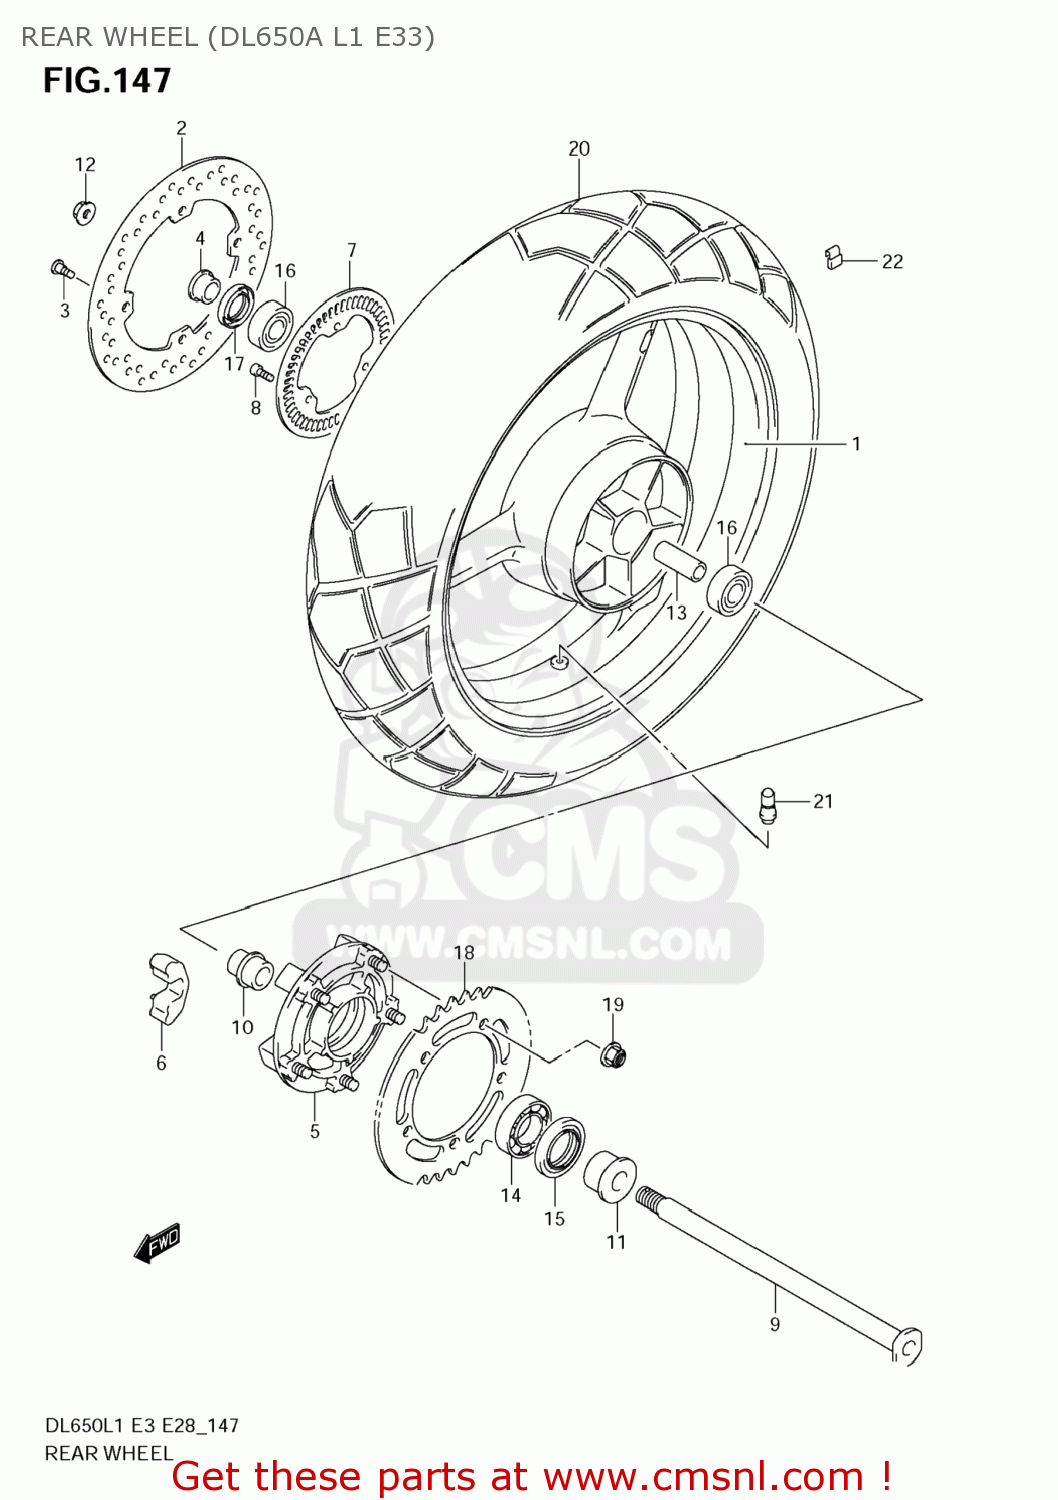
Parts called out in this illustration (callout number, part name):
1	WHEEL,RR(17M/CXMT4.00)
2	DISC,RR BRAKE
3	BOLT(8X21)
4	SPACER,RR AXLE,R
5	DRUM, REAR SPROCKET
6	ABSORBER,RR HUB SHOCK
7	RING,SPEED SENSOR FR(50T)
8	BOLT
9	AXLE,RR
10	RETAINER,RR SPROCKET DRUM
11	SPACER,RR AXLE,L
12	NUT
13	SPACER(20.8X27.2X124)
14	BEARING
15	SEAL,OIL(39X65X7)
16	BEARING
17	SEAL,OIL(28X47X7)
18	SPROCKET,RR(47T-525)
19	NUT
20	TIRE,REAR,150/
21	VALVE ASSY,WHEEL RIM(TR412)
22	WEIGHT,WHEEL BALANCE 10G
